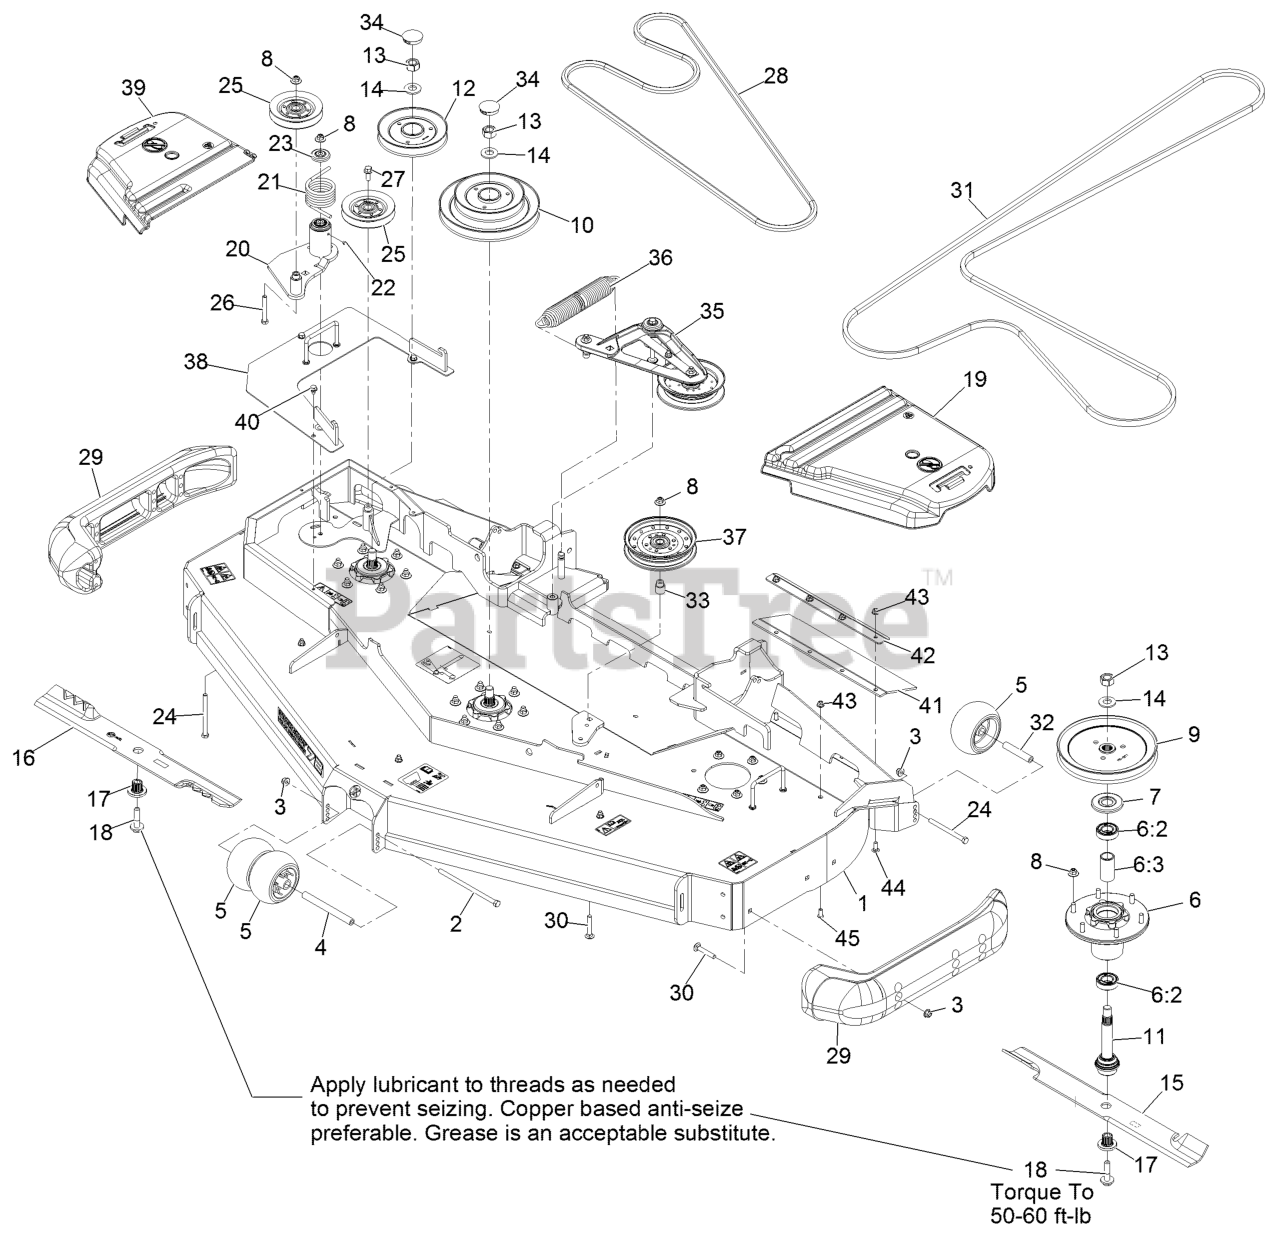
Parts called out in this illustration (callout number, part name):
1	DECK-RD72 NLZ, W/DECALS
2	SCREW-HH
3	NUT-HF, NI
4	SPACER-WHEEL
5	ROLLER-SCALP, ANTI
6	ASM-CUTTER HSG WITH BEARINGS
6:2	BEARING-BALL
6:3	SPACER-BEARING
7	GUARD,BEARING TOP .989
8	Nut-Nyloc 3/8-16 Flg
9	SHEAVE,BLADE DRIVE 8.74
10	SHEAVE, DOUBLE 72RD
11	ASM-SPINDLE AND SEAL
12	SHEAVE-RD REV DRIVE SERIE
13	NUT-HEX
17	BUSHING,SPLINED
18	SCREW,SEMS 1/2-20 X 2.19
19	COVER-BELT, LH
20	IDLER ASM
21	SPRING-TORSION
22	FITTING-GREASE
23	GUARD-TOP
24	SCREW-HH
26	SCREW-HH
27	SCREW-HHF
29	SKID-BUMPER, DECK
30	Bolt-Carriage 3/8-16 X 2 1/4
31	BELT
32	TUBE-SPANNER
33	BUSHING-IDLER
34	PLUG,BLACK NYLON 1.75
35	DECK IDLER ASM
36	SPRING-EXTENSION
38	COVER-REVERSE DRIVE
39	COVER-BELT, RH
41	GUARD-TIRE
42	SUPPORT-OUTER FLAP
43	NUT-HF, NI
44	SCREW-CARR
45	SCREW-HSBH
